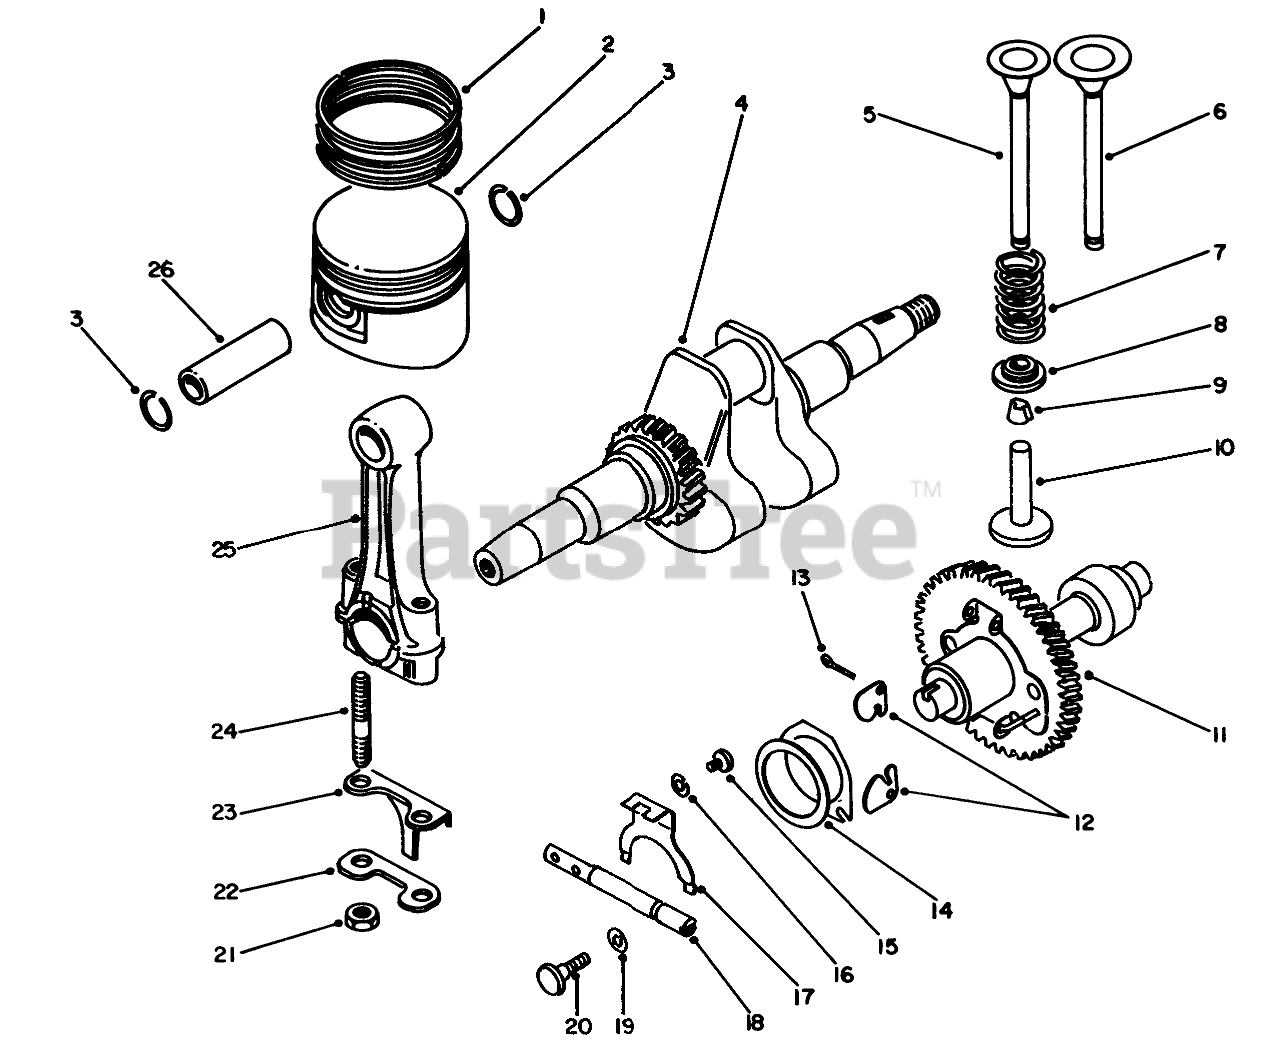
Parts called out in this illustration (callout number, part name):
1	RING SET
2	Piston
3	Circlip
4	Crankshaft
5	EXHAUST VALVE
7	Spring
8	Retainer
9	Cotter
10	Tappet
11	Camshaft
13	Cotter Pin
14	Spacer
15	Screw
16	Lockwasher
17	PLATE
18	Shaft
19	Gasket
20	Screw
21	Nut
22	LOCK PLATE
23	Plate-Splash
25	Connecting Rod (Incl. Ref. #21-24)
26	PISTON PIN
